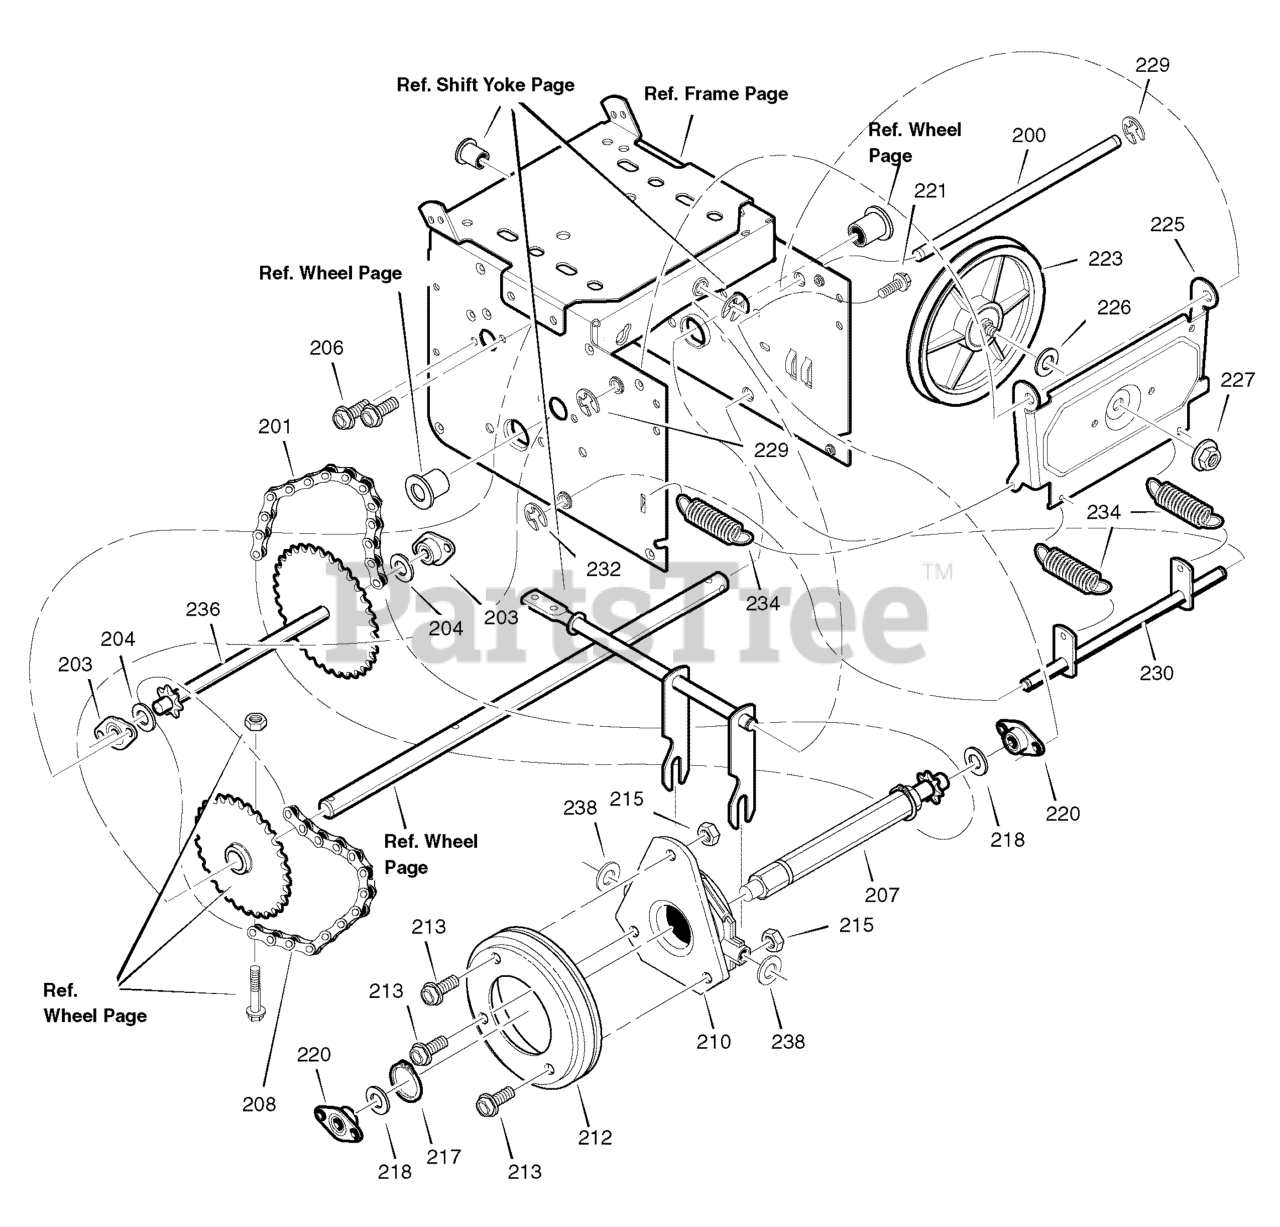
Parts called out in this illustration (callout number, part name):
200	LF AXLE, SWING PLATE YZ
201	CHAIN, ROLLER #420 X 19.00
203	BEARING AND RETAINER, ASSEMBLY
206	SCREW, TAP 5/16-18 X 0.5
207	HEX SHAFT ASSEMBLY
208	CHAIN, ROLLER #420 X 18.00 LG
210	BEARING, TRUNION CLUTCH R
212	WHEEL, FRICTION DISC
215	NUT, KEPS HEX 1/4-20
217	RING, RETEXT
220	BEARING AND RETAINER, ASSEMBLY
221	SCREW, TAP 5/16-18 X 0.5
223	FRICTION PULLY
225	LF PLATE, SWINGING YZ
226	SPACER, FRICTION PULLEY
227	NUT, FLANGE LOCK 3/8-24
229	RETAINER, RING
230	LF SPRING LINK YZ, ASSEMBLY
232	RETAINER, RING
234	SPRING, EXTENSION
236	SPOCKET, WELD INTERMED 33T/7
238	WASHER, FLAT
